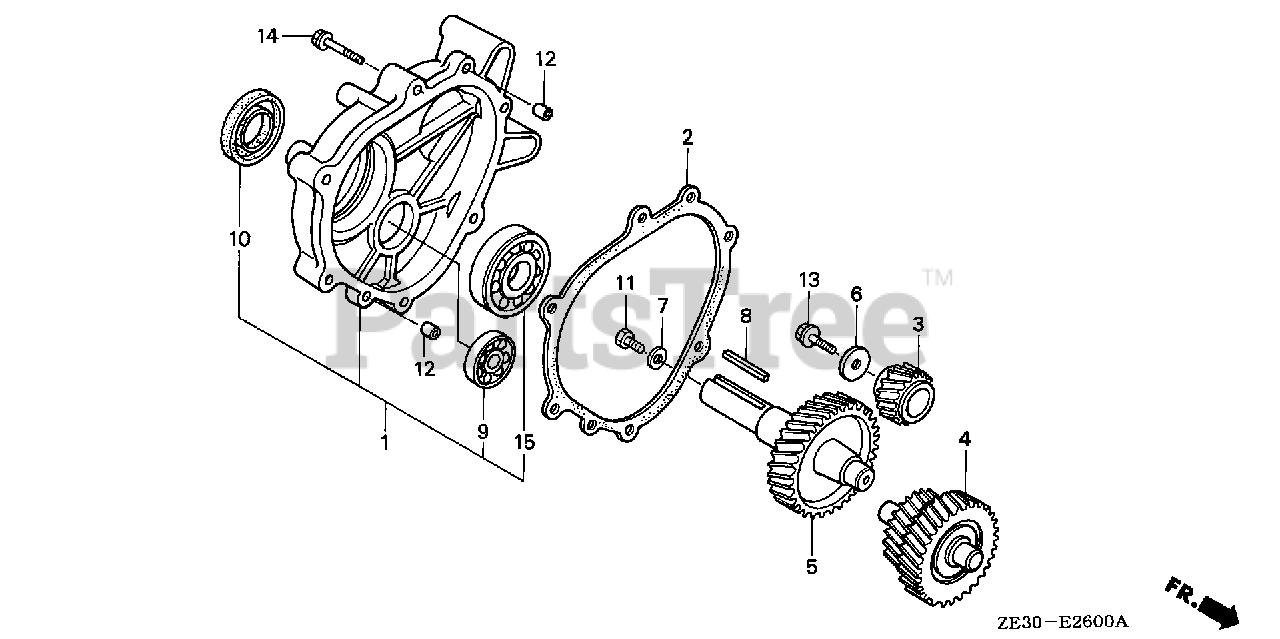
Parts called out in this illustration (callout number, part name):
1	COVER ASSY., GEAR CASE
2	GASKET, CHAIN CASE COVER
3	GEAR, PRIMARY DRIVE (22T)
4	COUNTERSHAFT (21T/27T)
5	SHAFT, P.T.O. (33T)
6	WASHER (8MM)
6	WASHER (8.5X42X4.5)
8	KEY (7X7X33) (OVER SIZE) (YELLOW)
9	BEARING, RADIAL BALL (6202) (NTN)
10	OIL SEAL (30X46X8)
12	PIN, DOWEL (8X14)
13	BOLT, FLANGE (8X25)
14	BOLT, FLANGE (8X40)
15	BEARING, RADIAL BALL (6206)
